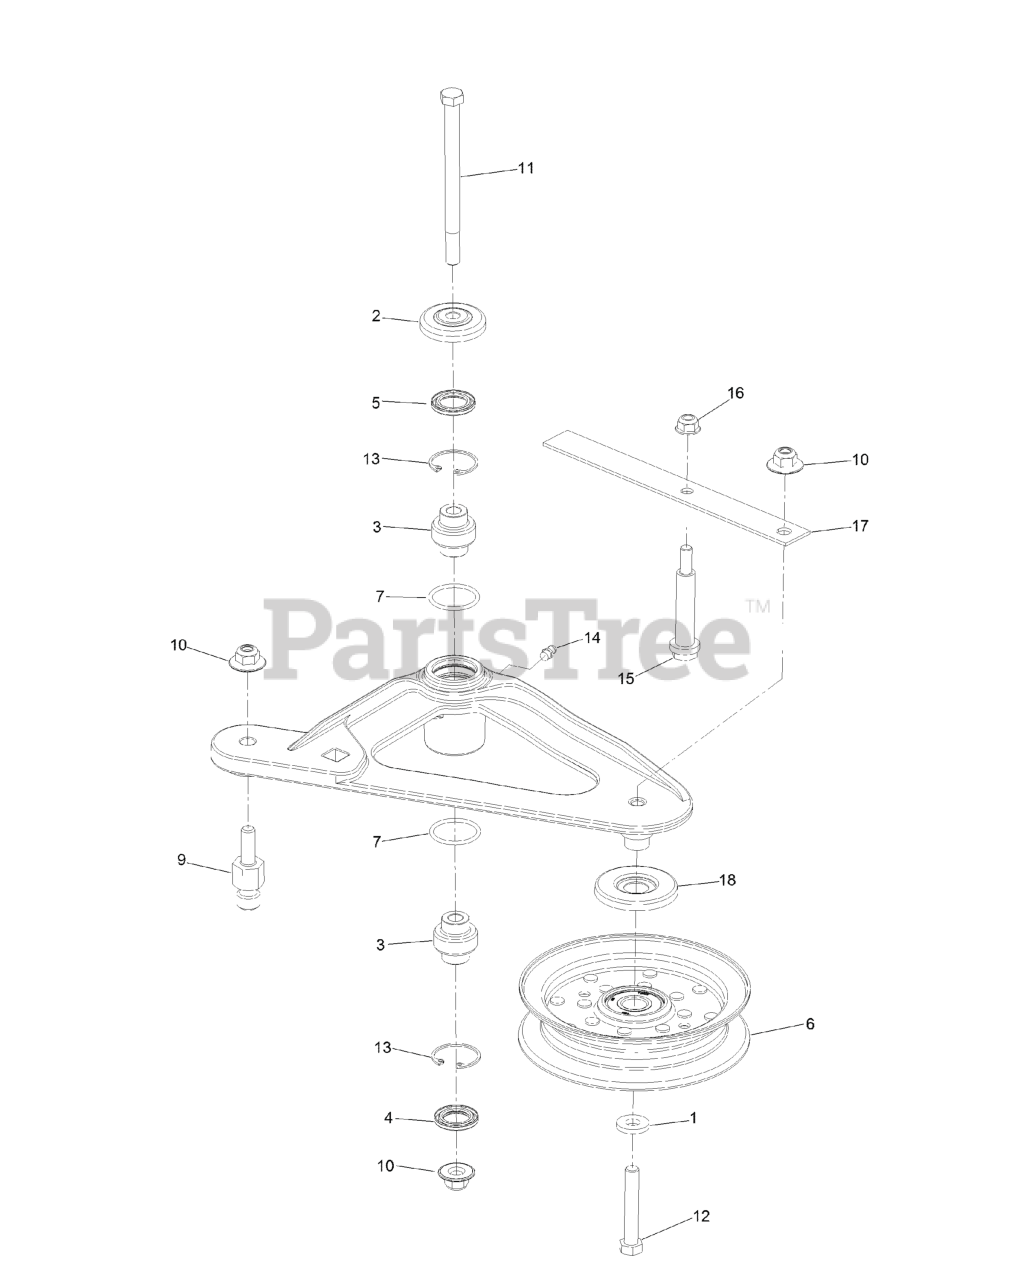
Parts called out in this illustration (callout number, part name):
2	GUARD-TOP
3	BEARING-SPHERICAL
4	SEAL-LIP, DOUBLE
5	SEAL-LIP, SINGLE
6	IDLER-PULLEY, FLAT
9	PIN-SPRING, ANCHOR
10	Nut-Nyloc 3/8-16 Flg
11	SCREW-SHOULDER, HH
12	SCREW-HH
13	RING-SNAP
14	FITTING-GREASE
15	BOLT-SHOULDER
16	NUT-HF, NI
17	SPRING-BELT
18	SHIELD-GUARD, DUST
